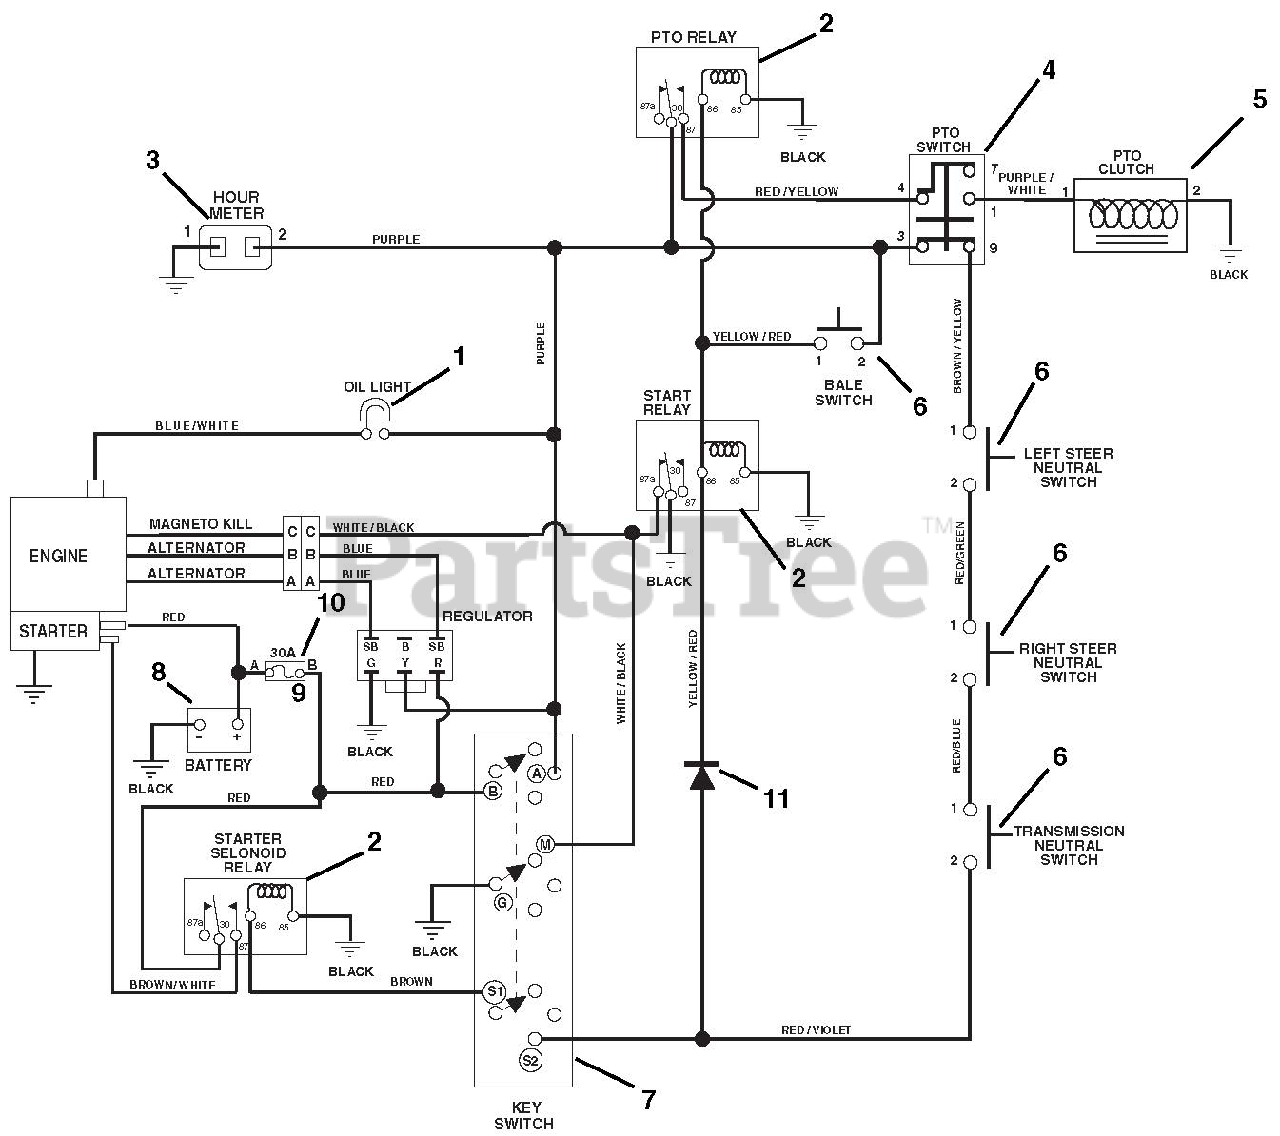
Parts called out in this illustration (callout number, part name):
1	Light, Indicator
2	Relay
3	Hour Meter
4	Switch, Clutch w/ Retainer
5	Clutch, Electric
6	Switch, Bale
7	Key Switch
8	Cable, Battery to Starter
9	Cable, Negative Battery
10	Fuse, 30 AMP
11	Molded Diode Plug, 1 AMP
